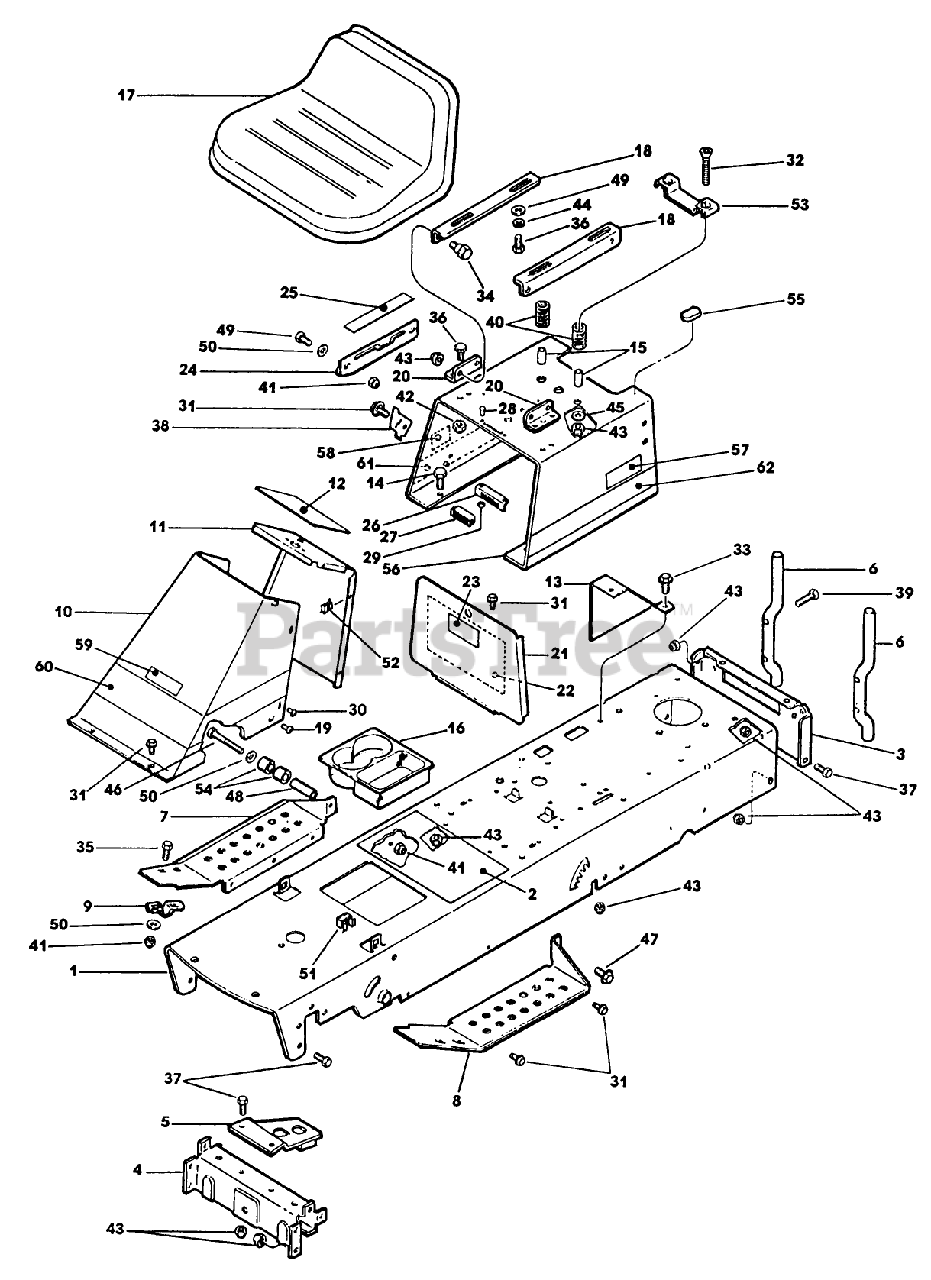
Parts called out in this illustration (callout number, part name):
3	HITCH PLATE* G
5	STEERING BRKT WA*G
11	STEERING TOWER W/D(12)
25	Decal-Shift Pattern
31	SCREW-THREAD FRMG
33	SCREW-HWH
35	SCREW
36	SCREW - HEX
38	PLATE, LOCK* G
40	SPRING
41	NUT-LOCK, CONE
42	NUT
43	NUT-LOCKING
45	WASHER
54	SPACER - RUBBER
55	BUMBER - SEAT
